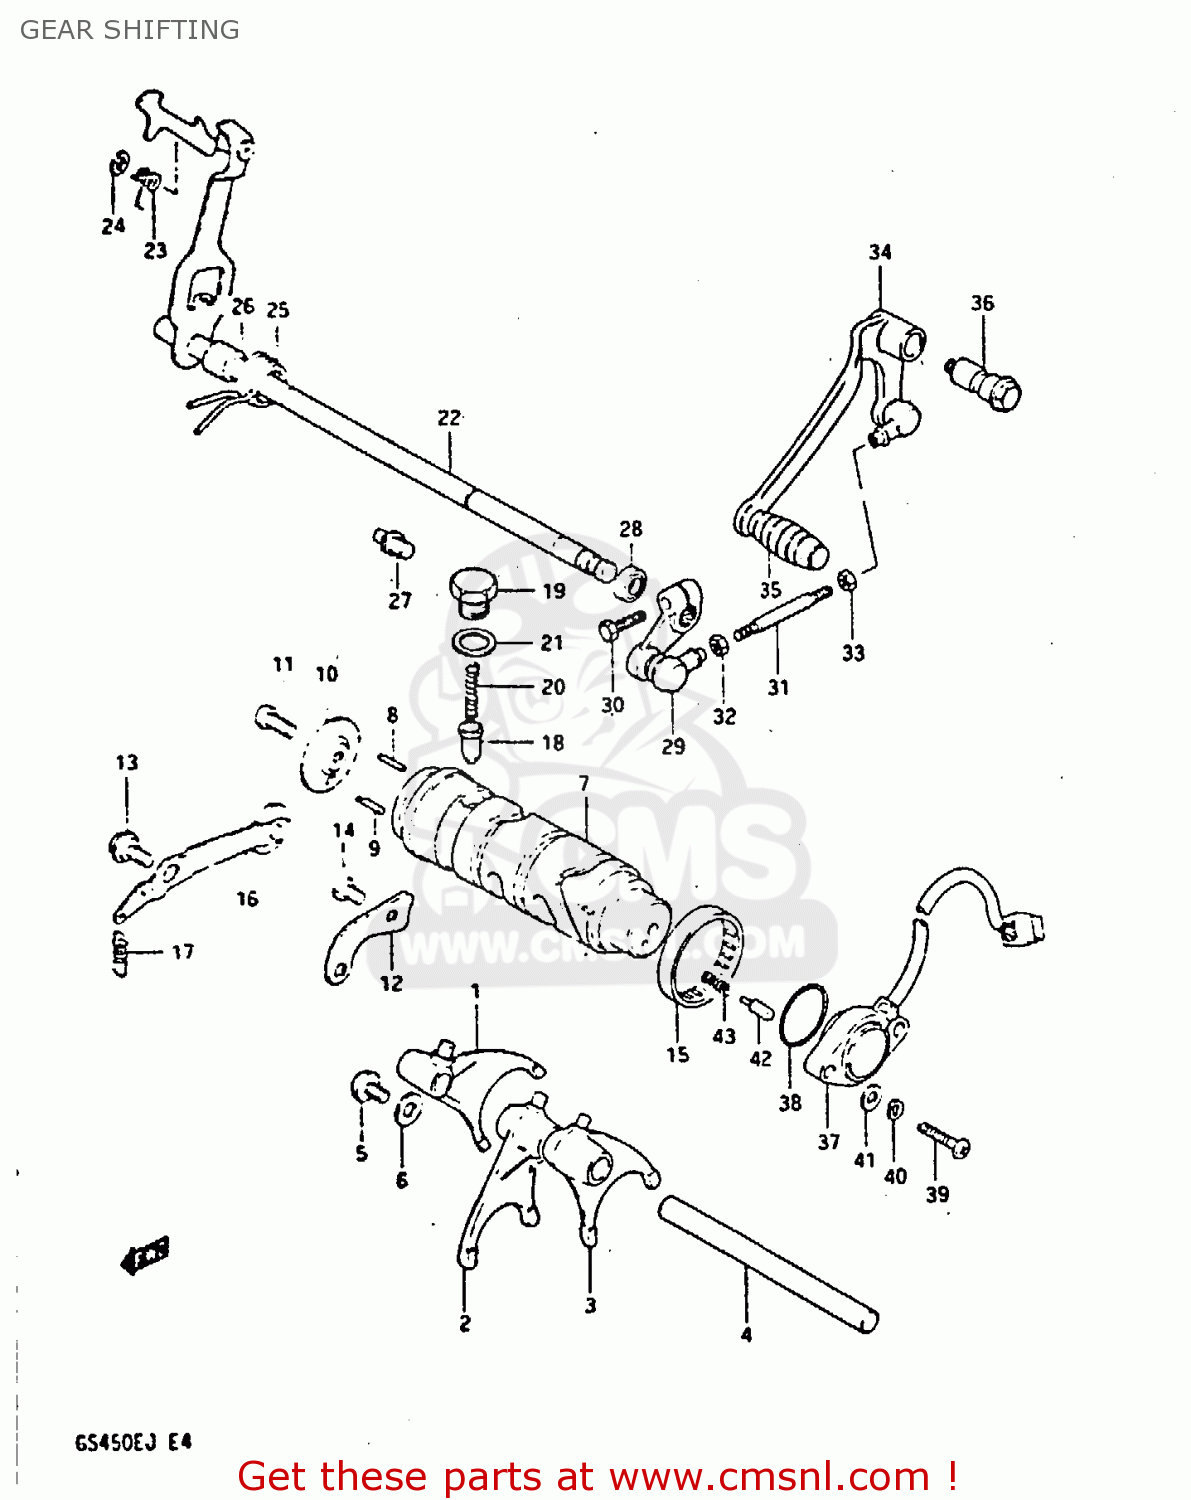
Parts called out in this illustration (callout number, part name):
1	FORK,GEAR SHIFT NO.1
2	FORK,GEAR SHIFT NO.2
3	FORK,GEAR SHIFT NO.2
4	SHAFT,GEAR SHIFT FORK
5	SCREW
6	WASHER
7	CAM,GEAR SHIFT
8	PIN(4X18.5)
9	PIN
10	RETAINER,GEAR SHIFT CAM DR PIN
11	SCREW
12	GUIDE,GEAR SHIFT CAM
13	BOLT
14	BOLT
15	BEARING(40X47X12)
16	STOPPER,GEAR SHIFT CAM NO.1
17	SPRING
18	STOPPER,GEAR SHIFT CAM NO.2
19	HOLDER,GEAR SHIFT CAM STOP SPR
20	SPRING
21	GASKET(14X19.2X2) (NAS)
22	SHAFT,GEAR SHIFT
23	SPRING
24	E RING
25	SPRING
26	SPACER(12X20X15.3)
27	STOPPER,GEAR SHIFT CAM
28	OIL SEAL
29	ARM,GEAR SHIFT LINK
30	BOLT
31	ROD,GEAR SHIFT LINK
32	NUT 6MM
33	NUT
34	LEVER ASSY,GEAR SHIFT
35	RUBBER,GEAR SHIFT PEDAL
36	SHAFT,GEAR SHIFT LEVER
37	BASE ASSEMBLY,NEUTRAL SWITCH TERMINAL
38	O-RING (D:2.4 ID:26.2)
39	SCREW
40	LOCK WASHER
41	WASHER
42	PIN(5X15.5)
43	SPRING
